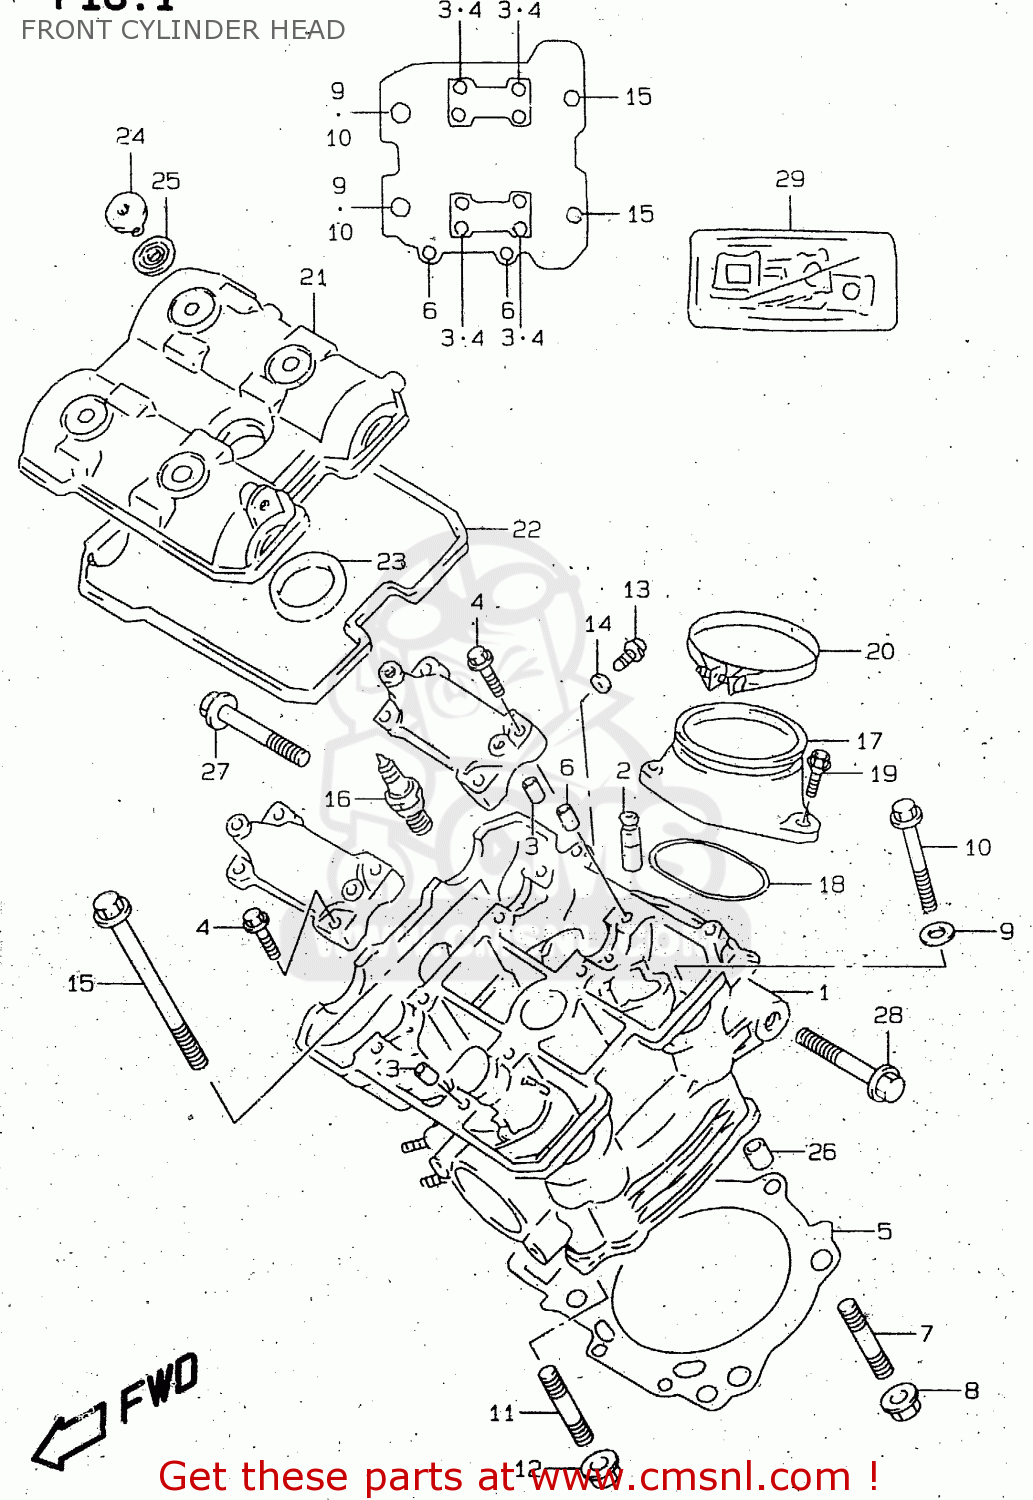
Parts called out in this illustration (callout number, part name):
1	HEAD ASSY,CYLINDER
2	GUIDE,VALVE
3	PIN(6.2X8X11)
4	BOLT(6X39)
5	GASKET,CYLINDER HEAD (NAS)
6	PIN
7	BOLT,STUD
8	NUT
9	WASHER(10.5X19X2)
10	BOLT,CYLINDER HEAD(L:175)
11	BOLT,STUD
12	NUT
13	BOLT
14	GASKET(5.8X13X1.2) (NAS)
15	BOLT(6X70)
16	PLUG,SPARK(CR9EK)
17	PIPE ASSY,INTAKE
18	O RING(D:2.4,ID:55.6)
19	SCREW
20	CLAMP
21	COVER,CYLINDER HEAD FR
22	GASKET,CYL HEAD COVER NO.1 (NAS)
23	GASKET,CYL HEAD COVER NO.2
24	BOLT(7X17.5)
25	WASHER(10.6X25.5X2.3)
26	PIN(6.2X8X11)
27	BOLT
28	BOLT
29	GASKET SET (NAS)
